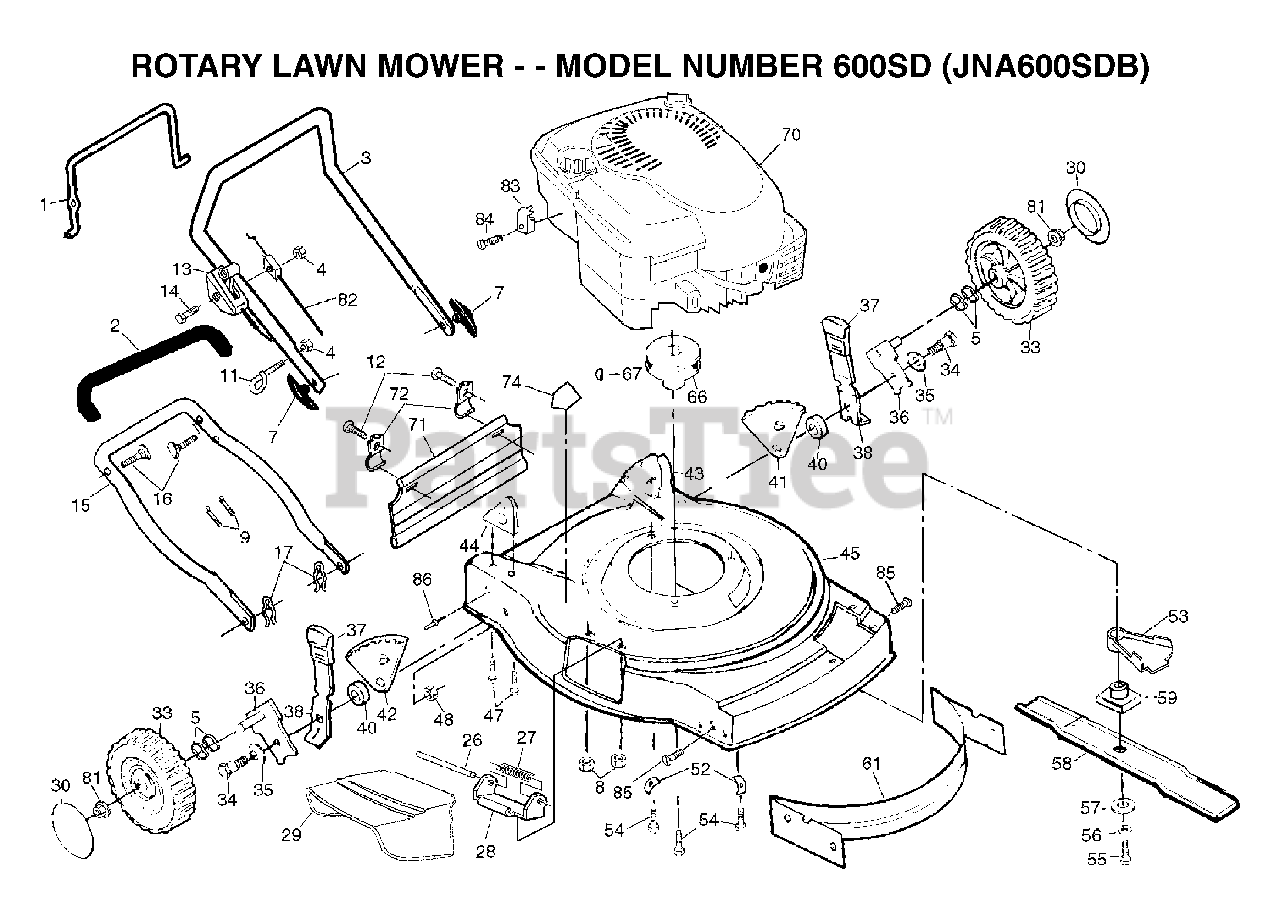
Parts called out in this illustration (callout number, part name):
1	CONTROL BAR ORANGE
2	GRIP.HANDLE.FOAM
4	NUT
5	WAVE WASHER
7	HANDLE KNOB
8	NUT
9	TIE GUIDE
11	ROPE, GUIDE
12	TAPPING SCREW
13	THROTTLE CONTROL
14	SCREW 1/4-20 X 2.12
15	LOWER HANDLE
16	HANDLE BOLT
17	HAIRPIN COTTER
26	ROD.HINGE.COMBI-C
27	SPRING PM
28	BRACKET PM
33	WHEEL.8X2.PR.LP.RAD.GREY
34	BOLT
35	BELLEVILLE WASHER
36	AXLE ARM
37	SELECTOR KNOB
40	RP SPACER HT ADJ
43	HANDLE BRACKET ASM. LH
44	HANDLE BRACKET ASM. RH
47	SCREW 5/16-18
48	LOCKNUT PM
53	SHIELD.DEBRIS.21.RWGD.EZ
54	BOLT 3/8-16X1-1/8
55	SCREW, HEX HD 3/8-24 X 1-3/8
56	LOCKWASHER
57	WASHER,HARDEN
58	22" BLADE (FOR MODEL 56 SFEB)
59	RP BLADE ADAPTOR
61	FRONT BAFFLE KIT
66	ENGINE.PULLEY.FWG
67	HI PRO KEY PM
71	REAR SKIRT
72	BRACKET DEFL PM
81	HEX FLANGE LOCKNT
82	ENGINE ZONE CONTROL CABLE
83	CABLE CLAMP(ENGINE)
84	SCREW.HEX.HEAD.WASHER.10-16
86	RIVET BLIND
